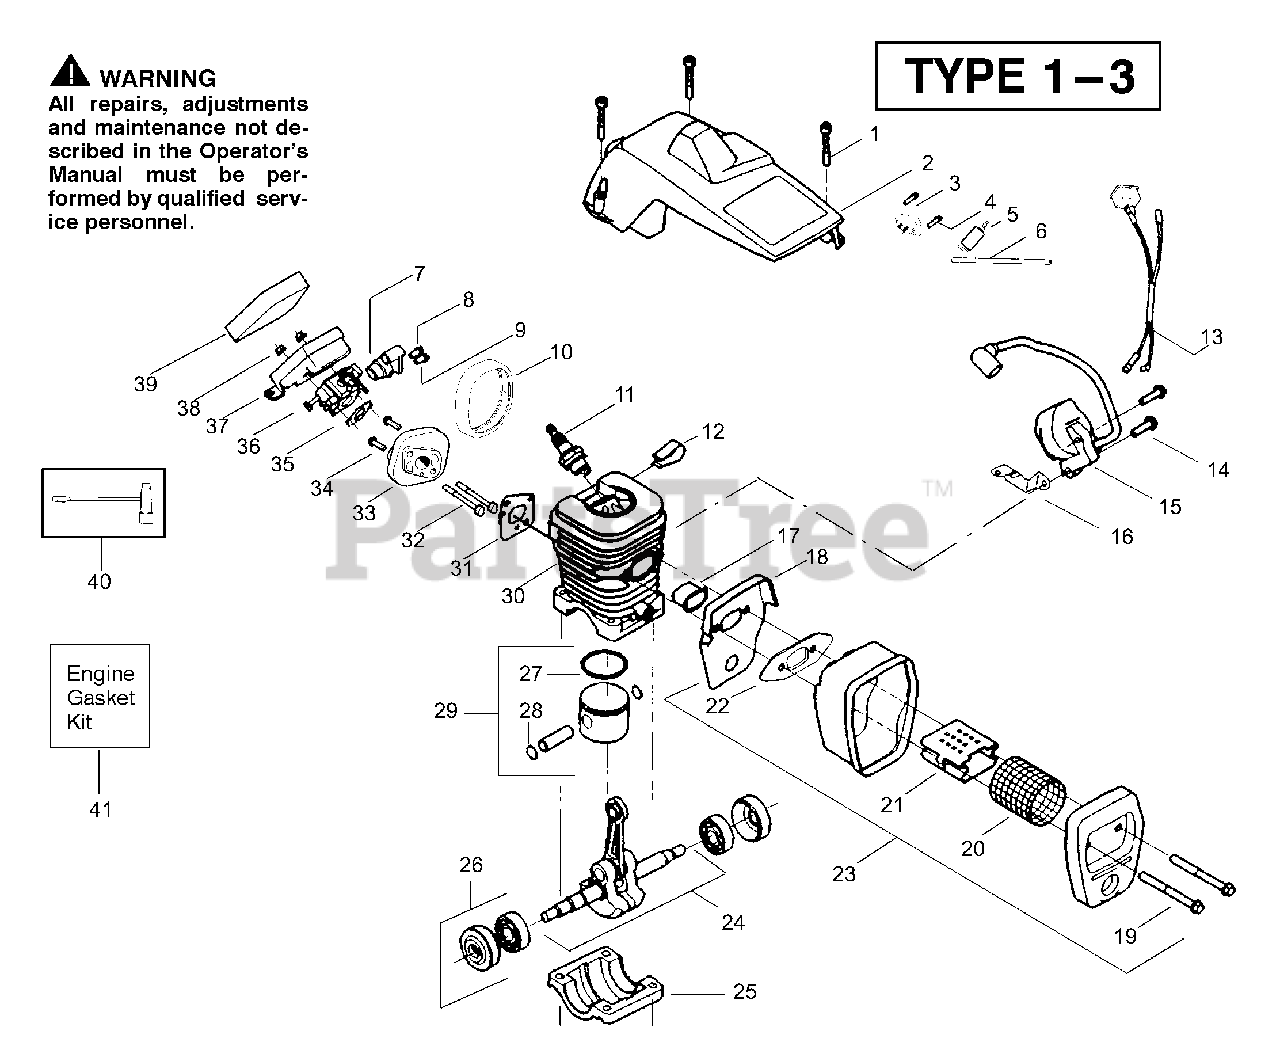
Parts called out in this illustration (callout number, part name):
2	Shield-Cylinder
3	Assy-Air Purge
5	Assy-Fuel Pick-up
6	Kit-Line Purge/Carb. (Small Dia)
7	Grommet-Carb Adjust.
8	Limiter Cap-High
9	Limiter Cap-Low
10	Seal-Carb Adapter
11	Spark Plug (RCJ-7Y)
12	Clip-High Tension Lead
13	Assy-Wire Harness
15	Module-Ignition
16	Strap-Ground
17	Insulator-Heat
18	Plate-Muffler Back
20	Screen-Spark
21	Muffler Diffuser
22	Muffler Gasket
23	Muffler Ass'y.
24	Assy-Crankshaft
25	Cap-Crankcase
26	Assy-Seal & Bearing
27	Ring-Piston
28	Retainer-Piston Pin
29	Kit-Piston
30	Kit-Cylinder
31	Gasket-Carb. Adapter
33	Adapter-Carb.
35	Carb. Gasket
36	Kit-Carburetor
37	Housing-Air Filter
39	Air Filter-Foam
40	Scrench
41	Kit-Engine Gasket
